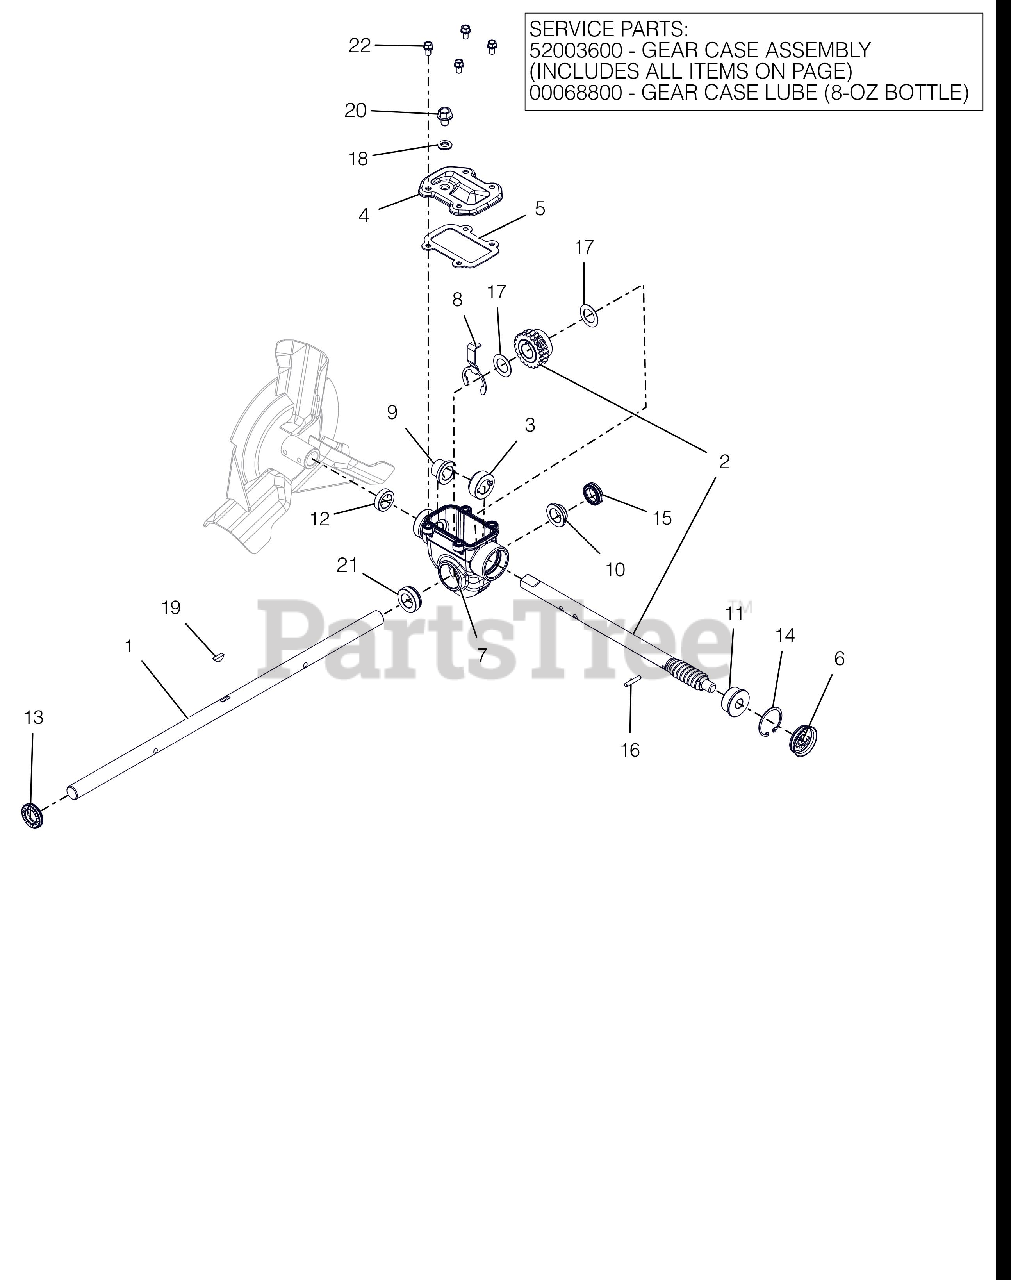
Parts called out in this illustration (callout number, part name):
1	SHAFT, RAKE - 22" (.750 DIA)
2	SHAFT AND WORM GEAR ASSEMBLY
3	THRUST COLLAR, .75" ID SLIPFIT
4	COVER, TOP - COMPACT
5	GASKET, TOP - COMPACT GEARCASE
6	COVER, GEAR CASE 1.50"
7	GEARCASE, COMPACT ALUMINUM
8	BUSHING RETAINER, COMPACT
9	BSHG-FLG .755X.878X.75X1.25
10	BSHG-FLG .755X.878X.424X1.25
11	BSHG-FLG .503X1.303X.62X1.465
12	SEAL-OIL .748X1.125X.312 TB2-H
13	SEAL-OIL .748X1.300X.250 TBC29
14	RG-RTNG-INT 1.500X.050
15	SEAL-OIL .748X1.125X.312 TBC29
16	PIN-STR .188X1.00 6150
17	WSHR-FL-STL .760X1.225X.032 YZ
18	WSHR-BND-SEAL .38X.75X.11 GALV
19	KEY-WDRF .19X.63 HRD #61
20	@SCR-ROLOK .38-16X.50 HWH YWZC
21	BSHG-FLG COMPACT, RIGHT
22	BOLT, SEMS .25-20X.50 GR5 YWZC
23	GEAR CASE, 24" ALUM SM TOP-LD
23	ARIENS L3 LUBE, 8 OZ BOTTLE
